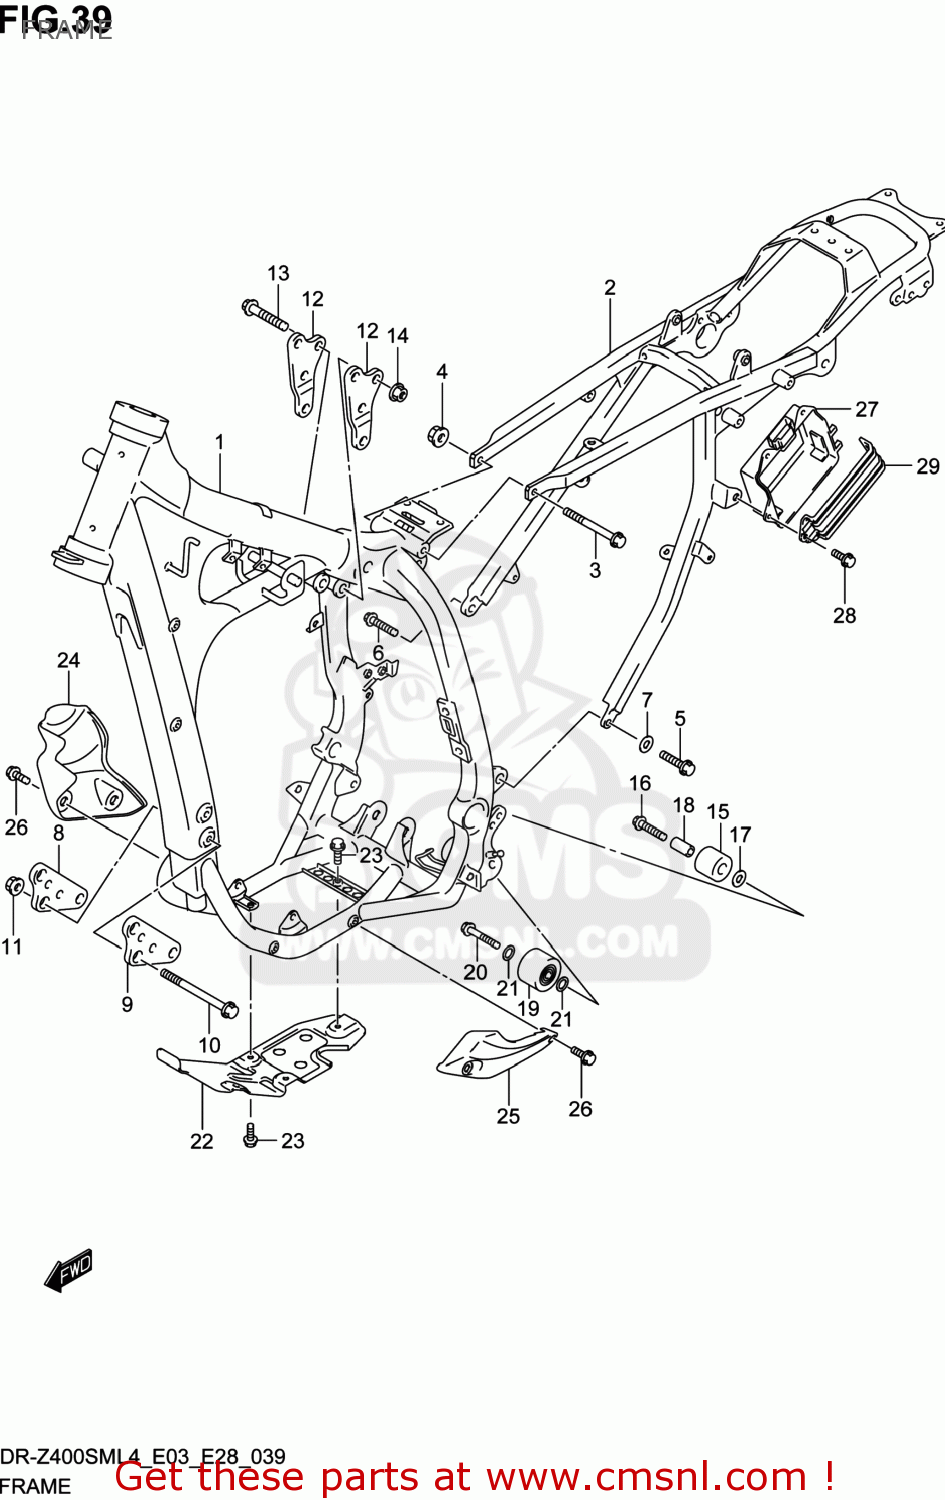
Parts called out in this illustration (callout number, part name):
1	FRAME(BLACK)
2	RAIL,SEAT
3	BOLT(8X115)
4	NUT
5	BOLT(8X18)
6	BOLT(8X20)
7	WASHER(8.5X18X2)
8	PLATE,ENG MTG FR
9	PLATE,ENG MTG FR
10	BOLT(8X90)
11	NUT
12	PLATE,HEAD MTG RR
13	BOLT(8X50)
14	NUT
15	ROLLER,CHAIN CONTROL UPR
16	BOLT(8X41)
17	WASHER
18	SPACER(8.6X12.2X26.5)
19	ROLLER,CHAIN
20	BOLT(8X41)
21	SHIM(8X12X1)
22	PROTECTOR,ENGINE
23	BOLT
24	GUARD,WATER PUMP
25	GUARD,MAG COVER
26	BOLT(8X16.5)
27	HOLDER,BATTERY
28	BOLT(6X17.8)
29	BAND,BATTERY HOLDER
